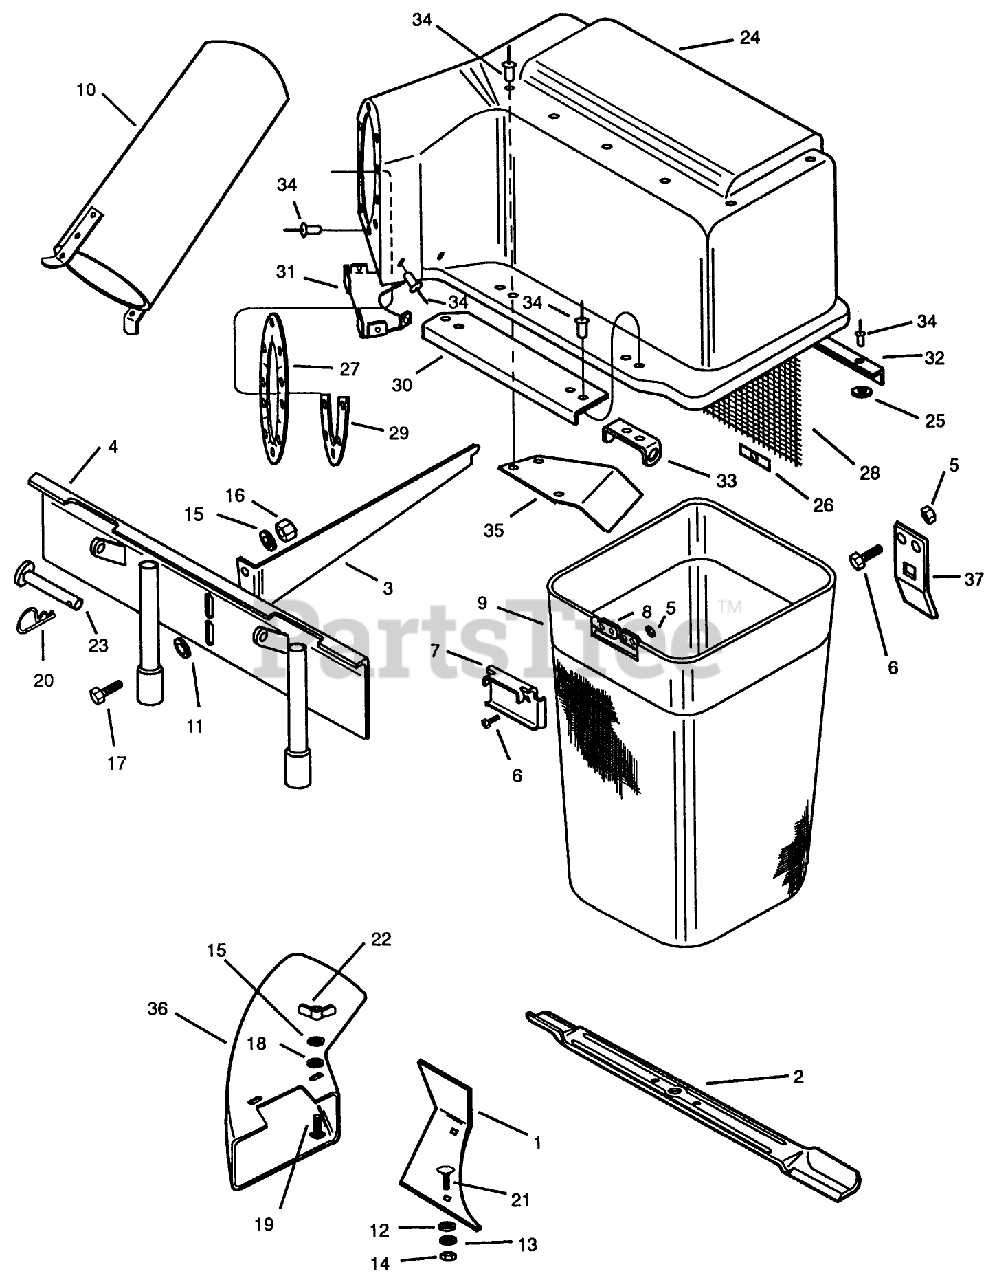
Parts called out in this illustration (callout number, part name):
1	DEFLECTOR-CHUTE
3	BAR - COVER LATCH
4	FRAME ASSY *B
5	NUT-LOCK, CONE
6	SCREW
9	GRASS BAS ASSEMBLY
10	TUBE ASSY
14	NUT
16	NUT SS
19	BOLT - CARRIAGE
20	PIN-HAIR
24	COVER & DECAL ASSY
32	ANGLE - COVER *B
